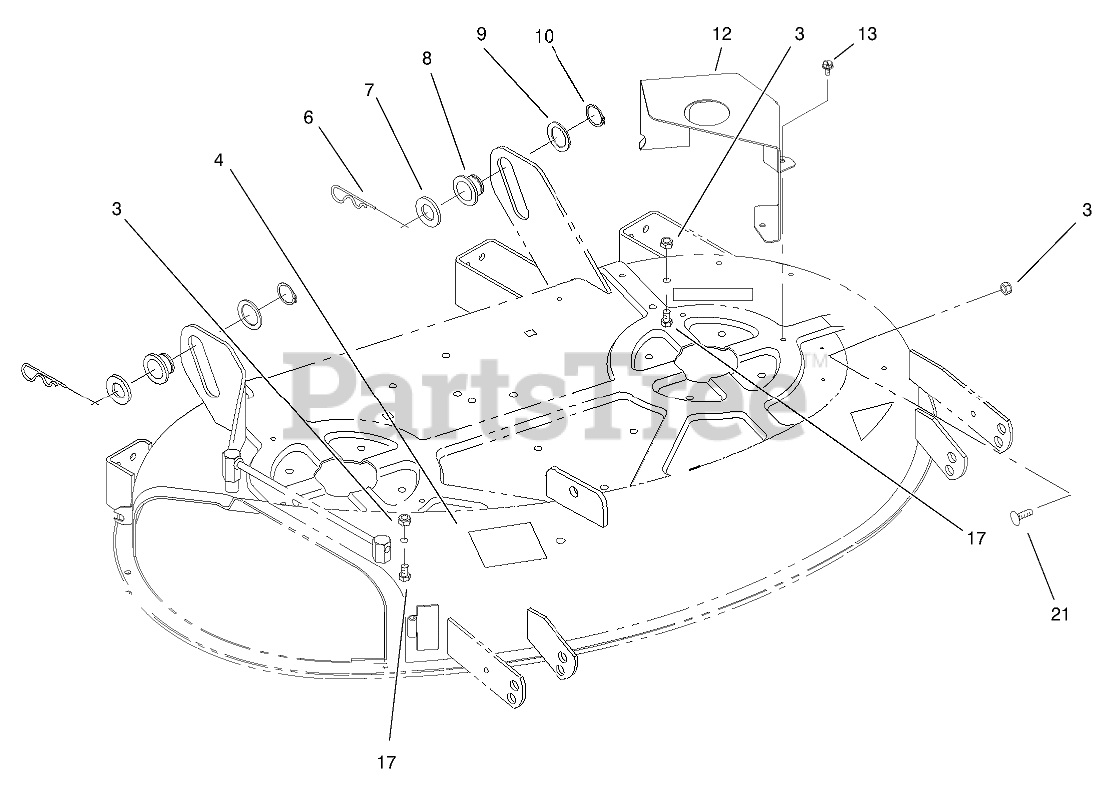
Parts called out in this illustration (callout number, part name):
3	NUT-LOCK, NI
4	DECAL-ROUTING, BELT
6	PIN-HAIR
7	WASHER-FLAT
8	ROLLER-LIFT
9	WASHER
10	RING-RETAINING
12	COVER-BELT
13	SCREW-HWHTF
17	SCREW-HH
21	SCREW-CARR
